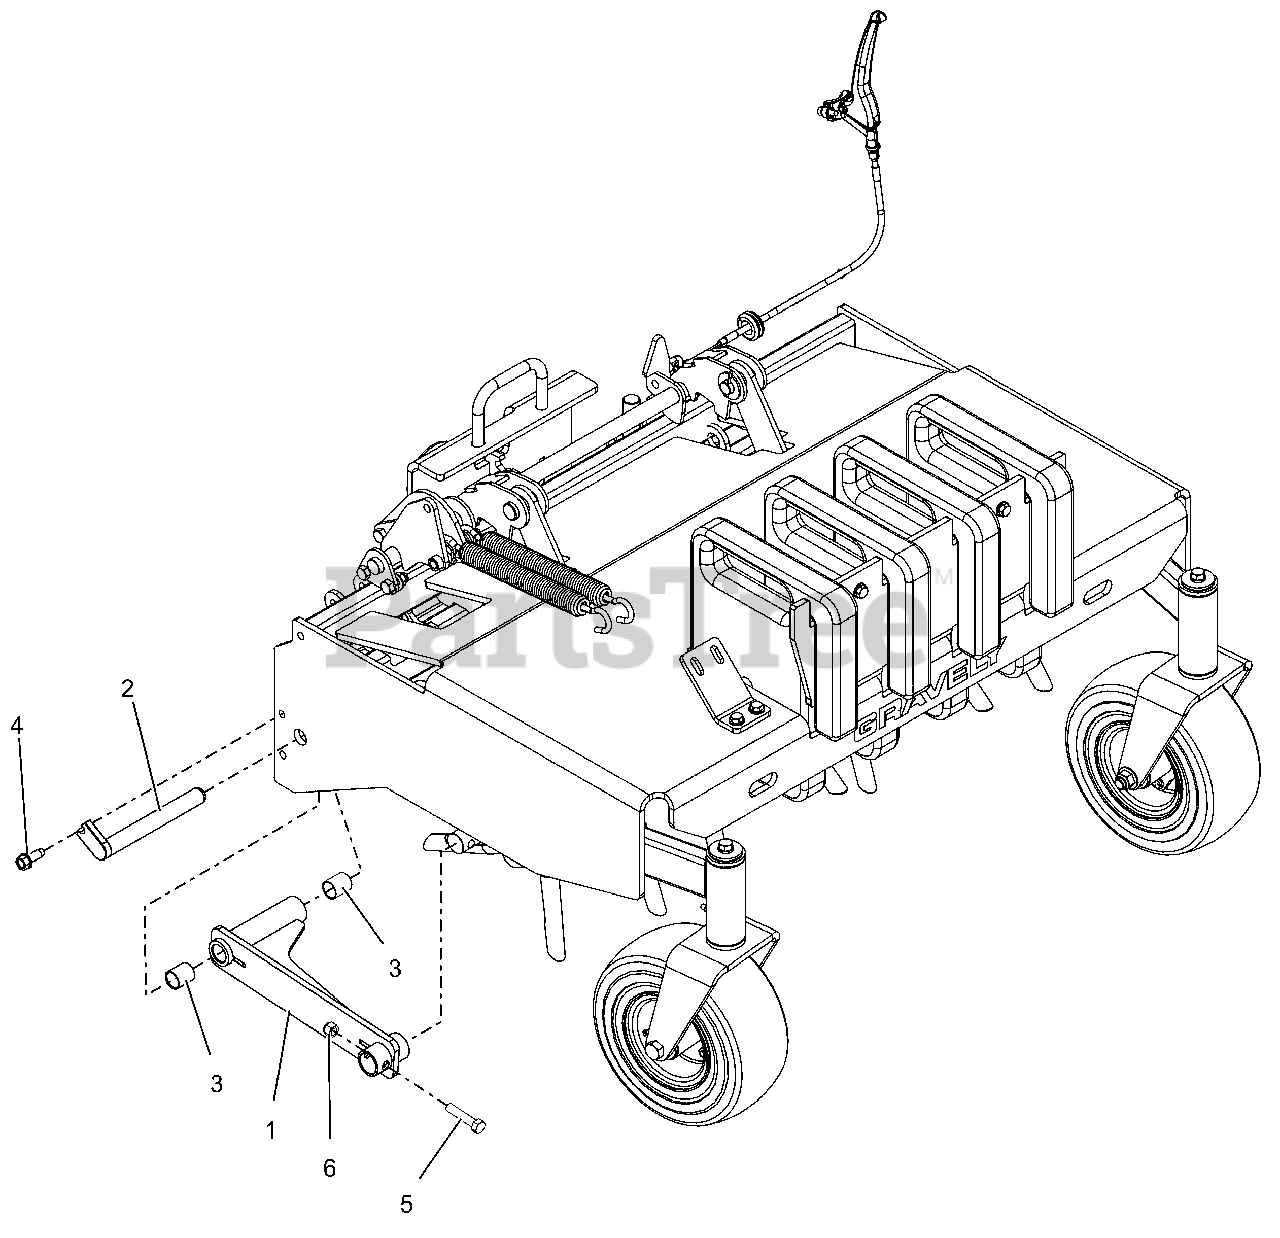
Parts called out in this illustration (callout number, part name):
1	WLDMT, BRACE - BLACK
2	PIN, MOWER MTG
3	BRG, .750 X .875 X 1.000
4	SCR-TAP .38-16X1.00 HWH TR ZCC
5	BLT, HEX .38-16X1.75 G5 ZCC
6	NUT,NYL .38-16 G5 ZCC
